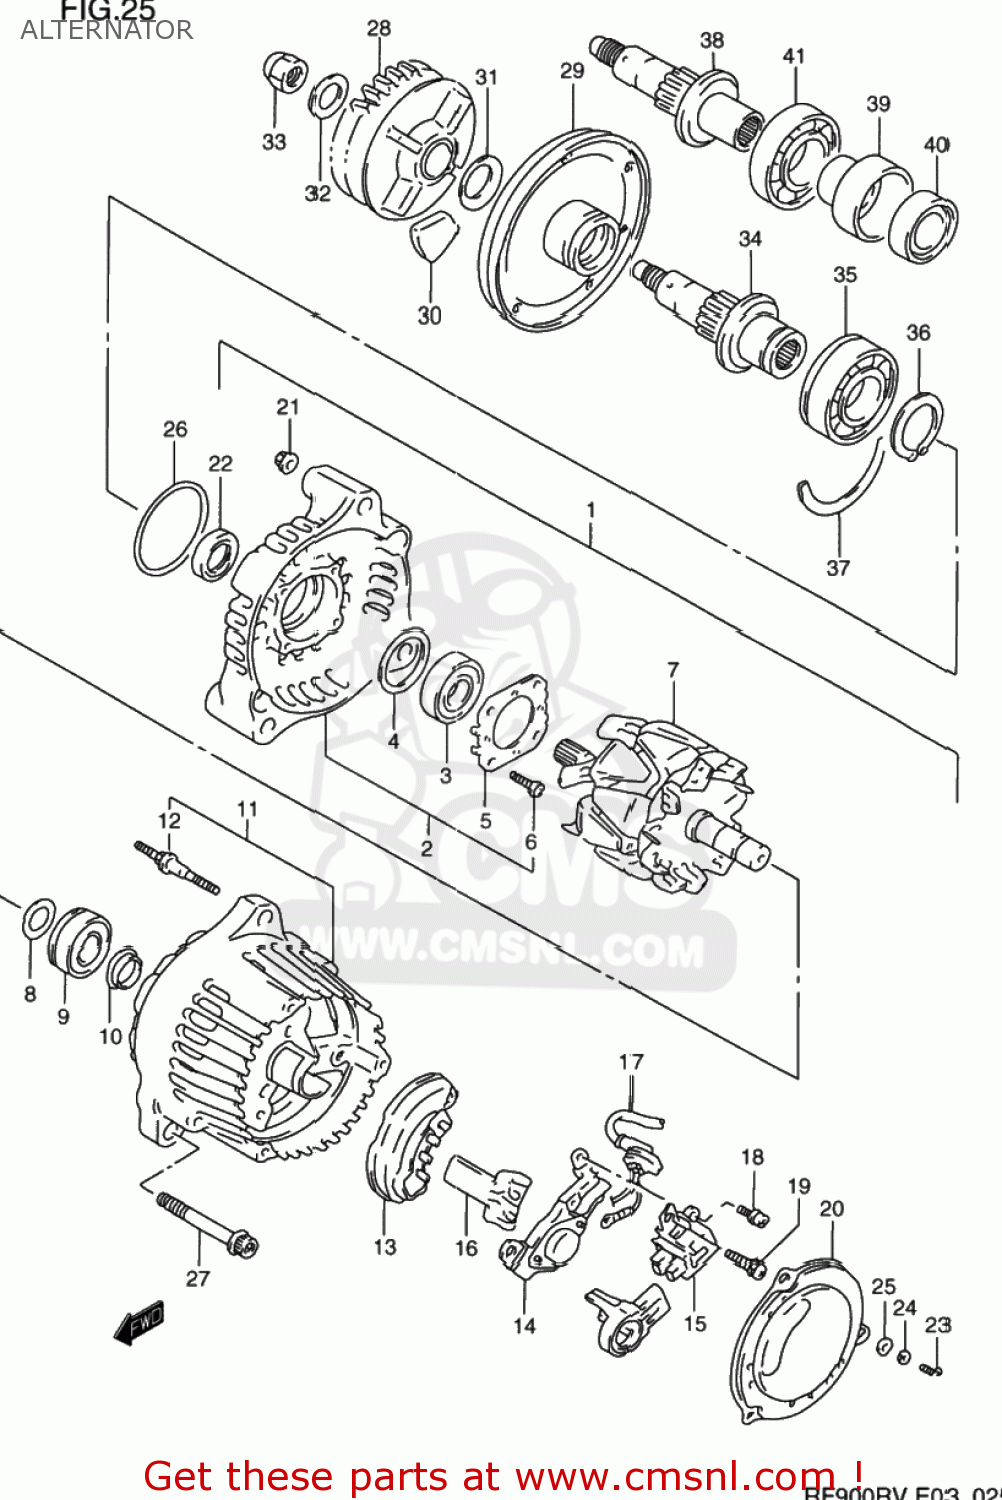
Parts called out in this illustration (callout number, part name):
1	ALTERNATOR ASSY
2	FRAME,DRIVE END
3	BEARING
4	COVER,BEARING
5	RETAINER,BEARING
6	SCREW,BEARING RETAINER
7	ROTOR ASSEMBLY
8	COVER,BEARING
9	BEARING
10	COVER(2)
11	FRAME,END
12	STUD BOLT
13	HOLDER,RECTIFIER
14	REGULATOR
15	HOLDER,BRUSH
16	COVER,RECTIFIER
17	WIRE,LEAD
18	SCREW 4X6
19	SCREW
20	COVER
21	NUT
22	SEAL SET,OIL
23	SCREW
24	LOCK,WASHER
25	WASHER
26	O RING
27	BOLT
28	GEAR,GENERATOR DRIVEN
29	HOUSING,GENERATOR DAMPER
30	DAMPER,GENERATOR
31	WASHER
32	WASHER
33	NUT
34	SHAFT,GENERATOR DRIVE
35	BEARING(25X52X15)
36	CIRCLIP
37	C RING
38	SHAFT,GENERATOR DRIVE
39	HUB,GENERATOR DRIVE
40	COUPLING COMP,GENERATOR
41	BEARING(25X52X13)
